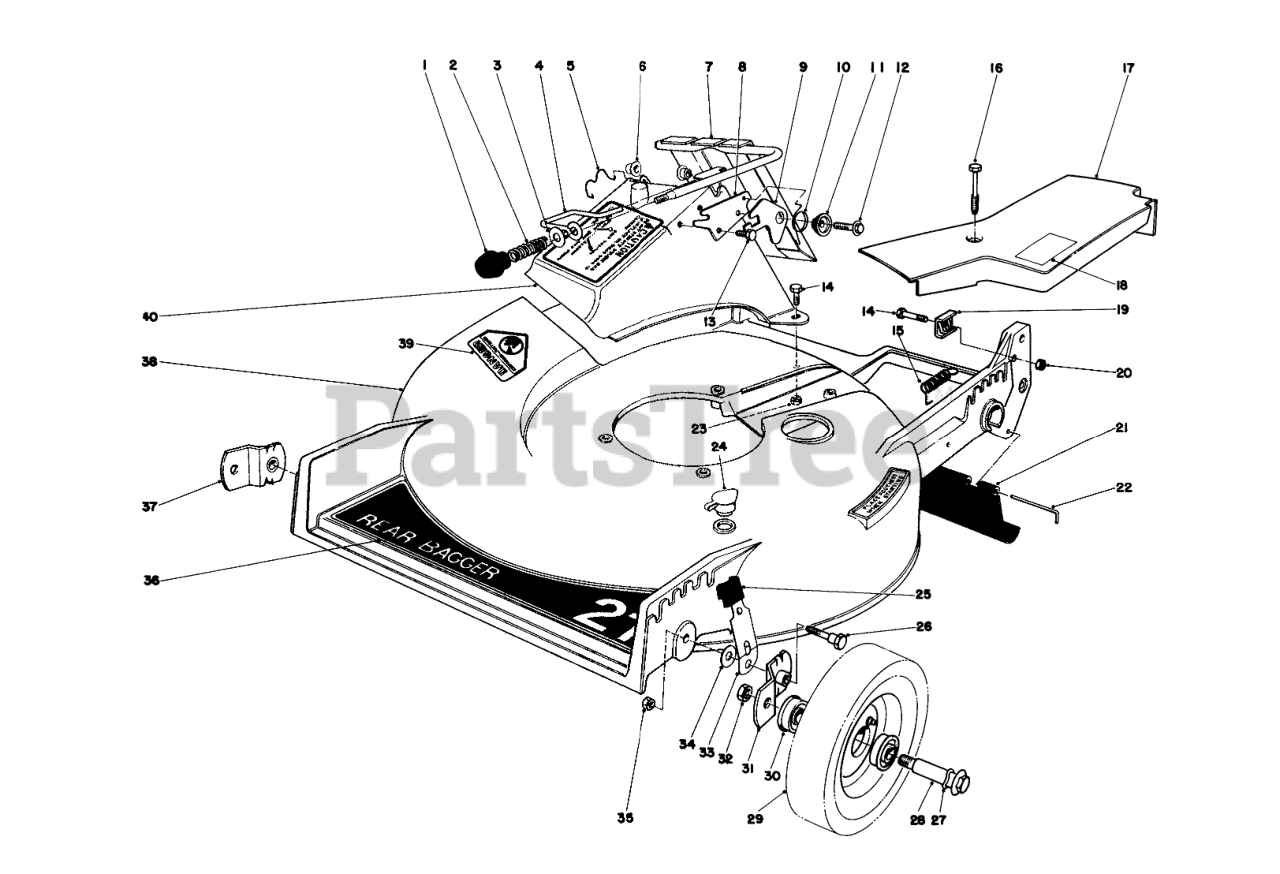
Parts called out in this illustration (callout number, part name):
2	COMPRESSION SPRING
3	WASHER
4	DOOR LATCH
5	DOOR RETAINER
6	BUSHING-NYLON
7	DOOR & HANDLE WA
8	DOOR LATCH PLATE
9	Latch Safety
10	TORSION SPRING
11	Latch Spacer
12	Screw
13	SCREW-HWH
14	SCREW-HH
15	IDLER SPRING
16	SCREW-HHFTF
17	Belt Cover
18	Sticker Grease
19	CLAMP-CABLE
20	NUT-JAM
21	SHIELD - TRAILING
22	Rod Shield
23	NUT-LOCK, NI
24	WASHOUT PLUG
25	KNOB-ARM
26	PIVOT SCREW
27	SPRING WASHER
29	Wheel & Tire Assembly (Incl. Ref. #30
30	BEARING-BALL
31	PIVOT ARM ASM A
32	Nut
33	SPRING ARM ASM (R&S)
34	WASHER-PIVOT
35	Nut
36	Decal-Deck
37	PIVOT ARM ASM B
38	Housing
39	DECAL-DANGER
40	DISCHARGE CHUTE B
